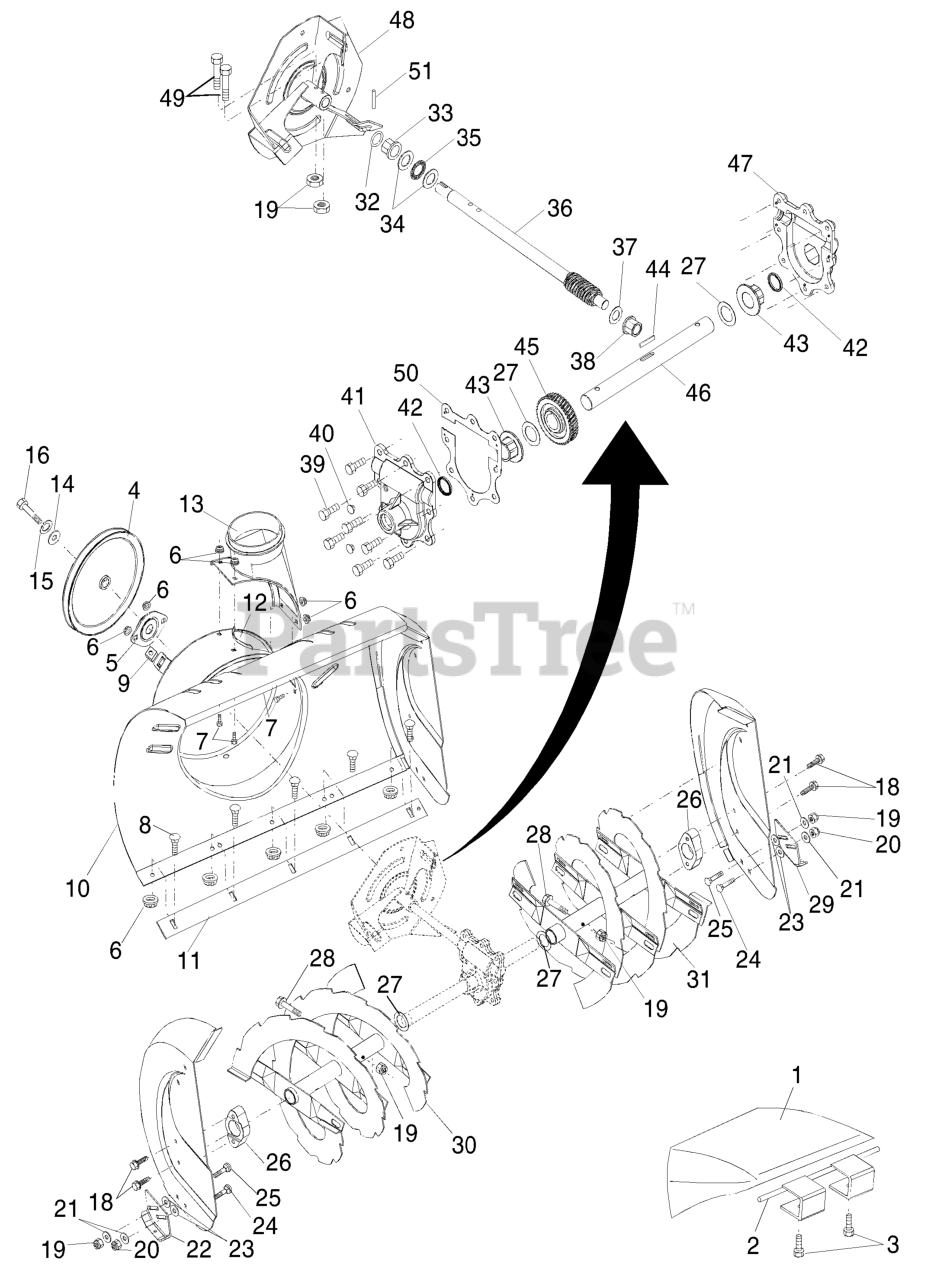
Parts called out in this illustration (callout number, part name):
1	WEIGHT BAG
2	WEIGHT BAG BRACKET
3	Screw, Hex Head 5/16-18 x 1-1/2
4	PULLEY, IMPELLER
5	BEARING ASSEMBLY FLANGE
6	NUT.FLANGE.5/16
7	BOLT.CARRIAGE.5/16-18X
8	BOLT
9	NUT, CAGE 3/8-16
10	RP HOUSING, AUGER 24"
11	BAR, SCRAPER 24"
12	BRACKET, CORNER DISCHARGE
13	BASE DISCHARGE CHUTE
14	STEEL WASHER
15	WASHER.LOCK.HVY.HLCL.SPR.5/16
16	Screw, Hex Head 5/16-18 x 3/4
18	SCREW, HEX HD 5/16X1
19	LOCKNUT.NYLOC.1/4-20
20	NUT.71038.31-18.HEX.NYLOCK
21	WASHER.20X8.5
22	SKID PLATE RH
23	WASHER, NYLON FRICTION
24	BOLT
25	BOLT, SHOULDER
26	BEARING, AUGER
27	WASHER TRUST 1"
28	BOLT, SHOULDER 1/4-20 X 2
29	SKID PLATE LH
30	AUGER ASSY RH 24
31	AUGER ASSY LH 24
33	BUSHING FLANGE 3/4
34	WASHER, THRUST 3/4
35	BEARING TRUST 3/4 NTA-1220
36	SHAFT, IMPELLER
37	WASHER, THRUST 5/8
38	BUSHING.FLANGE.(.625X.75)
39	SELF-TAPPING SCREW 5/16-18X3/4
40	PLUG.AUGER.GEAR.BOX.SNOW
41	HOUSING.GEARBOX.RH.SNOW
43	BUSHING FLANGE 1"
44	KEY
45	WORM GEAR
46	SHAFT, AUGER
47	LH GEARBOX HOUSING
48	IMPELLER ASSY
49	SCREW.HEX.HD1/4-20X
50	GASKET.AUGER.GEARBOX
51	PIN, ROLL 3/16 X 1-1/8
